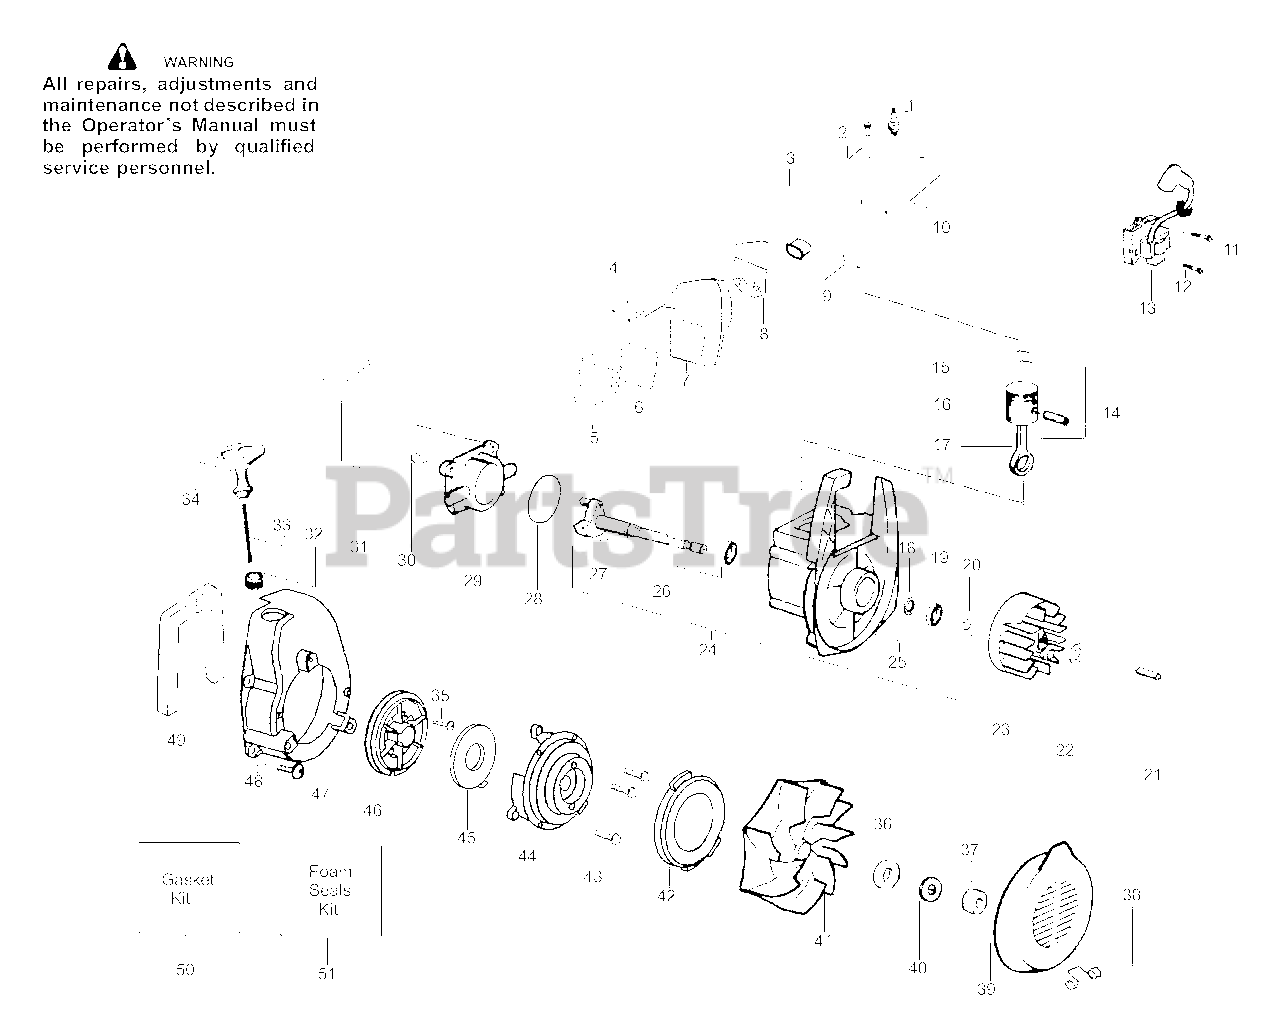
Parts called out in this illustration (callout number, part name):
1	Spark Plug (RCJ-6Y)
3	Insulator-Heat
6	Kit-Spark Screen
7	Kit-Muffler
8	Gasket-Baffle (kit)
9	Gasket-Cylinder (kit)
10	Kit-Cylinder
11	Grommet-Ign. Module
12	Screw-Ignition Module
13	Ignition Module
14	Kit-Piston
15	Piston Ring
16	Retainer-Piston Pin
17	Assy-Connecting Rod
18	Seal-Crankcase
19	Bearing-Outer
20	Retainer Ring-C'chaft
21	Spacer-Flywheel
23	Assy-Flywheel
24	Assy-Crankcase/Crankshaft
25	Assy-Crankcase
26	Bearing-Inner
27	Assy-Crankshaft
28	O-ring-C/case (kit)
29	Cover-Crankcase
30	Screw
31	Foam-219mm (kit)
32	Eyelet-Flange
33	Kit-Rope
34	Handle-Starter
35	Screw-Rope
36	Washer-Flat
38	Spring-Return Cover
39	Inlet Door
40	Washer-Belleville
41	Assy-Impeller
42	Seal-Ring
44	Housing-Pulley
45	Spring-Starter
46	Kit-Starter Pulley
47	Fan Housing
48	Screw
49	Foam-365mm (kit)
50	Kit-Gasket
51	Kit-Foam Seals
